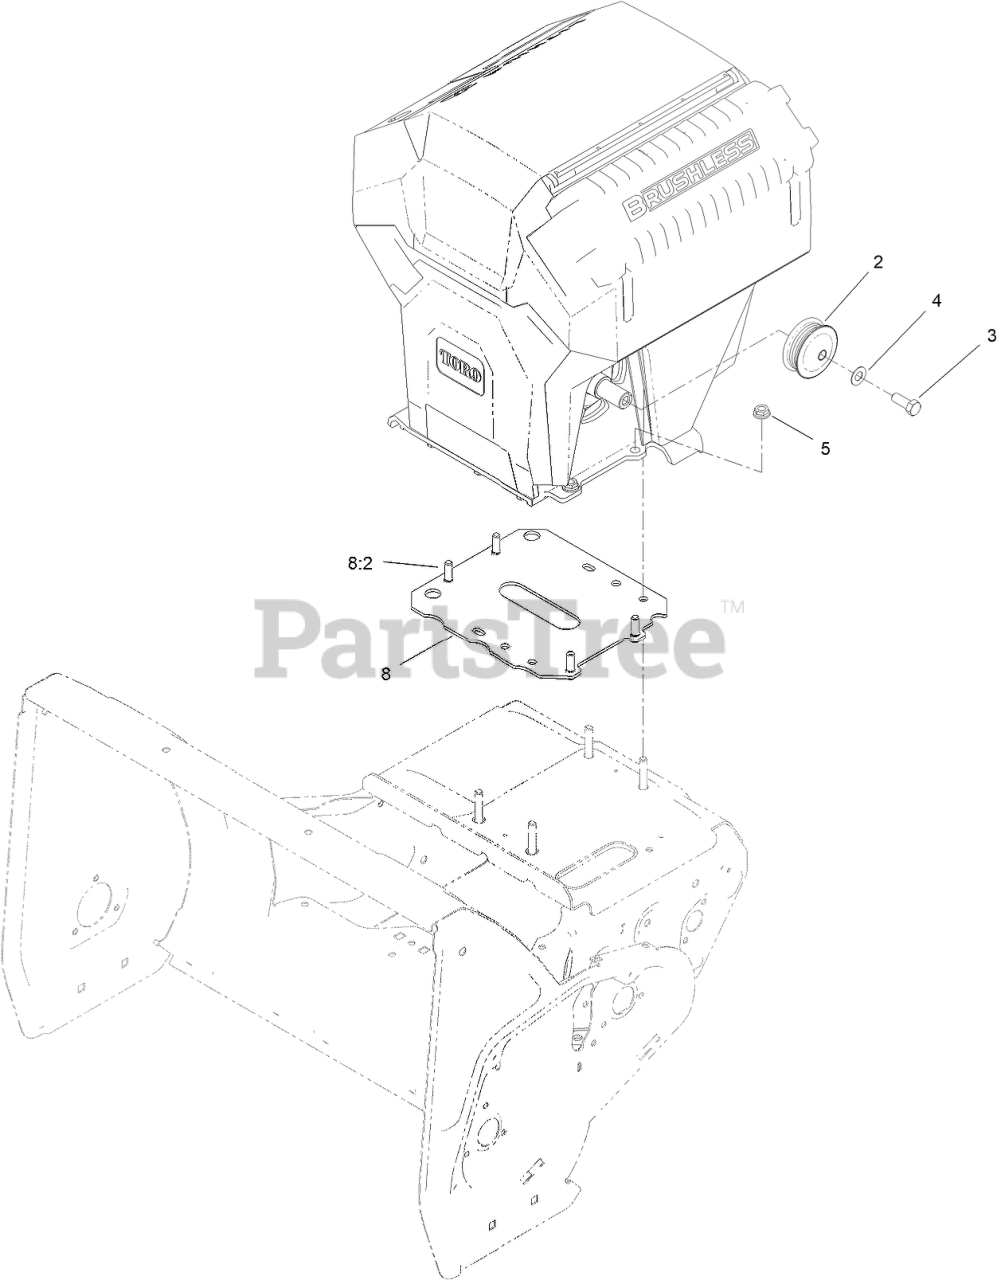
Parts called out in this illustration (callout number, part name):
2	PULLEY-ENGINE
3	SCREW-HH
4	WASHER-HARDENED
5	NUT-HF
8	ADAPTER ASM
8:2	STUD-PRESS
